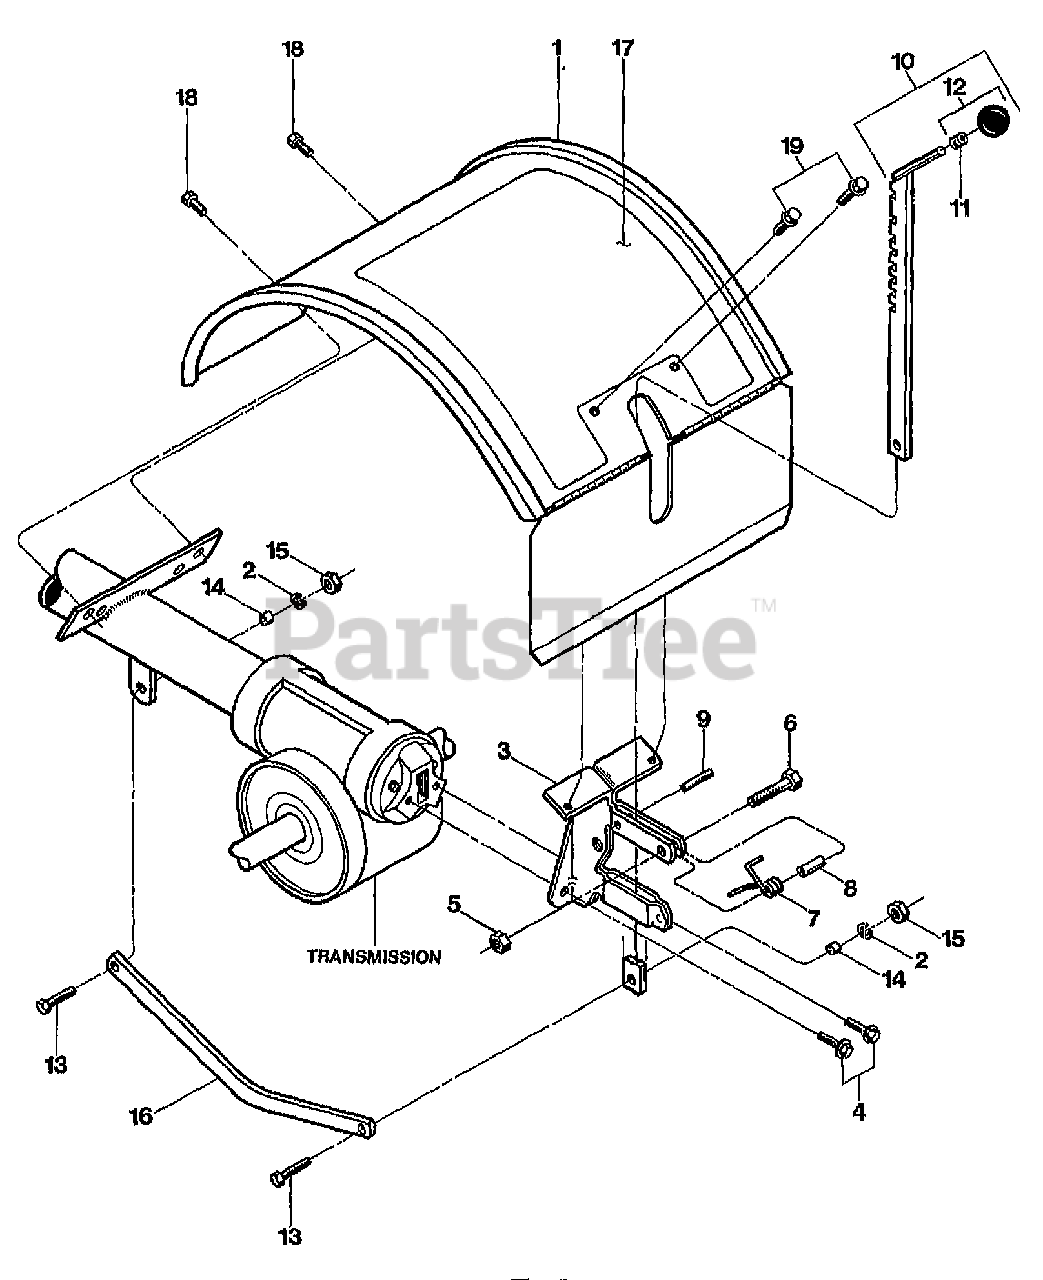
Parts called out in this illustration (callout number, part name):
1	HOOD W/DECALS JR (INCL. 17)
2	WASHER-LK .375
3	BRKT W/ROLL PIN (9308)(INCL. 9)
4	SCR-HFLK 5/16-18X.75
5	NUT-LK 1/4-20
6	SCR-HH 1/4-20X1.0
7	SPRING-TORSION
8	SPACER-.250X.343X.375
9	PIN-ROLL .25 X 1 (SPIRAL)
10	DEPTH REGULATOR W/KNOB (INCL. 11 & 12)
11	RING-TOLERANCE .5325 ID
12	KNOB-CONTROL (INCL. 11)
13	SCR-HH 3/8-16X1.25
14	BUSHING-.5X.375X.3
15	NUT-HEX 3/8-16
16	DRAG BAR-BENT
17	DECAL-HOOD JR
18	SCR-HWH 5/16-18 X .5 STH
19	SCR-HWH 1/4-20 X .5 STH (ATTACHES HOOD TO DEPTH REGULATOR BRACKET)
